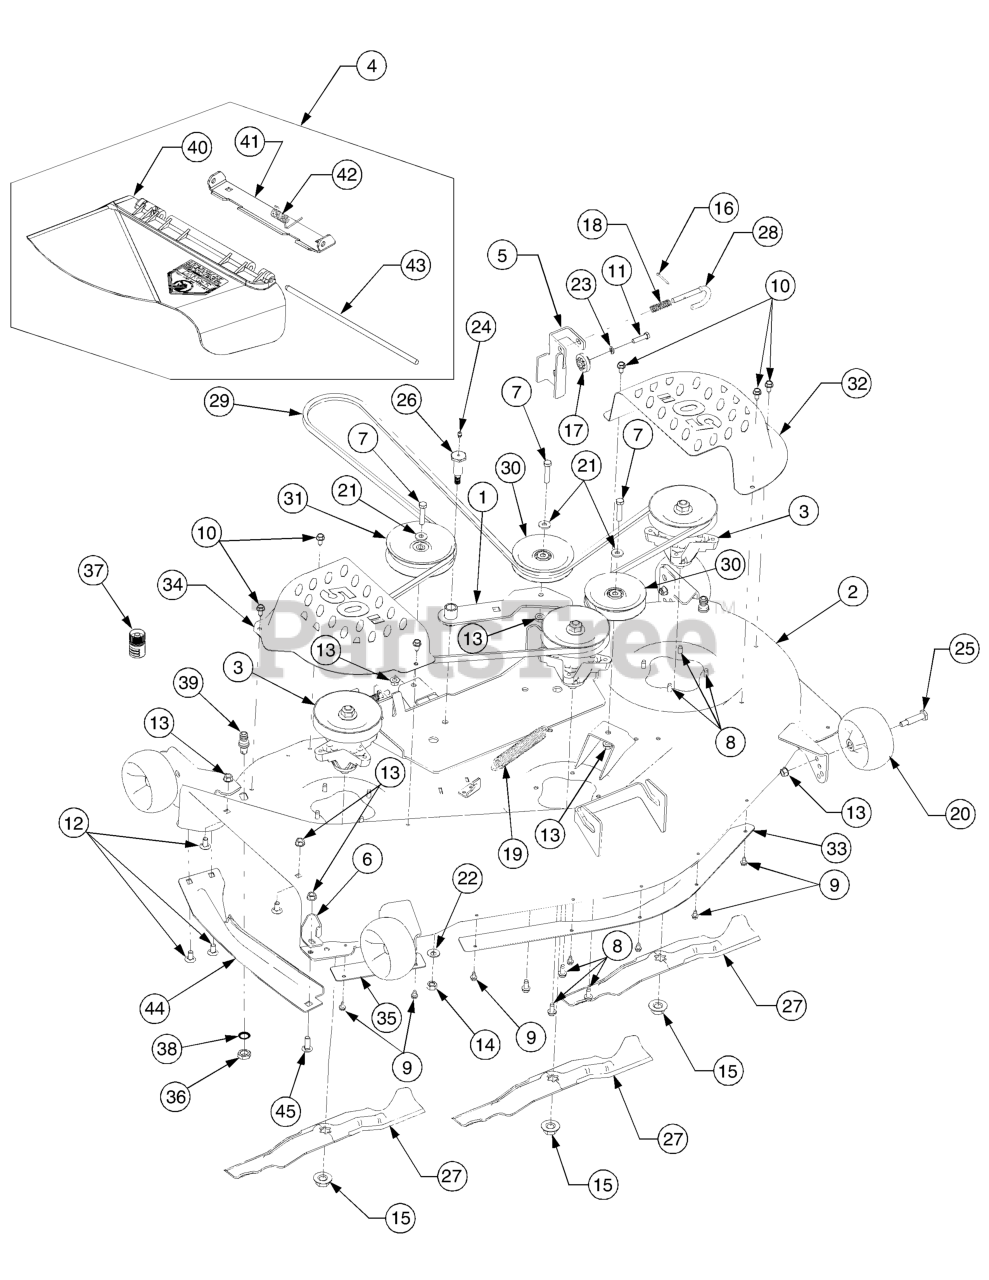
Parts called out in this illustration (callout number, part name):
2	Housing, Deck
2	Graphic, Danger
2	Graphic, Instruction
3	Spindle Assembly
4	Chute Assembly, Discharge
4	Graphic, Danger
7	Screw, Hex Cap, 3/8-16 x 1.75 GR5
8	Screw, Hex Wash. Hd. Tapp 5/16-18 x .75
9	Screw, Hex Wash. Hd. Tapp 1/4-20 x .5
10	Screw, Hex Wash. Hd. Tapp 5/16-12 x .75
11	Screw, Hex Cap, 5/16-18 x 1.25 GR5
12	Screw, Carriage, 3/8-16 x .75
13	Nut, Hex Flange Lock, 3/8-16 GRF ..
14	Nut, Hex, 7/16-14
15	Nut, Hex Flange, 5/8-18
16	Pin, Cotter, 1/8 x 1.25
17	Gear, Deck Adjustment
18	Spring, Compression
19	Spring, Extension, .94 Dia. x 6.74
20	Wheel, Deck Ball, 5.0
21	Washer, Flat, .38 x .93 x .110 HT
22	Washer, Bell, .45 x 1.0 x .062
23	Washer, Lock, 5/16
24	Fitting, Lube, 3/16 Drive
25	Screw, Shoulder, .498 x 1.53:3/8-16
26	Screw, Shoulder, .68 x 1.59
27	Blade, 2 in 1, 17.9 Lg
27	Blade, Hi-Lift, 17.9 Lg
28	Rod, Deck Hanger
29	Belt V, Type A Sec x 134
30	Pulley, Idler, 4.06 Dia
31	Pulley, Idler,
33	Skirt, Center
36	Nut, Hex, M16-1.5
37	Adapter, Water Nozzle
38	Washer, Lock
39	Nozzle, Deck Water
40	Chute, Deflector
41	Bracket, Chute Mounting
42	Spring, Torsion
43	Pin, Hinge
44	Guard, Finger
45	Screw, Carriage, 3/8-16 x 1.0
